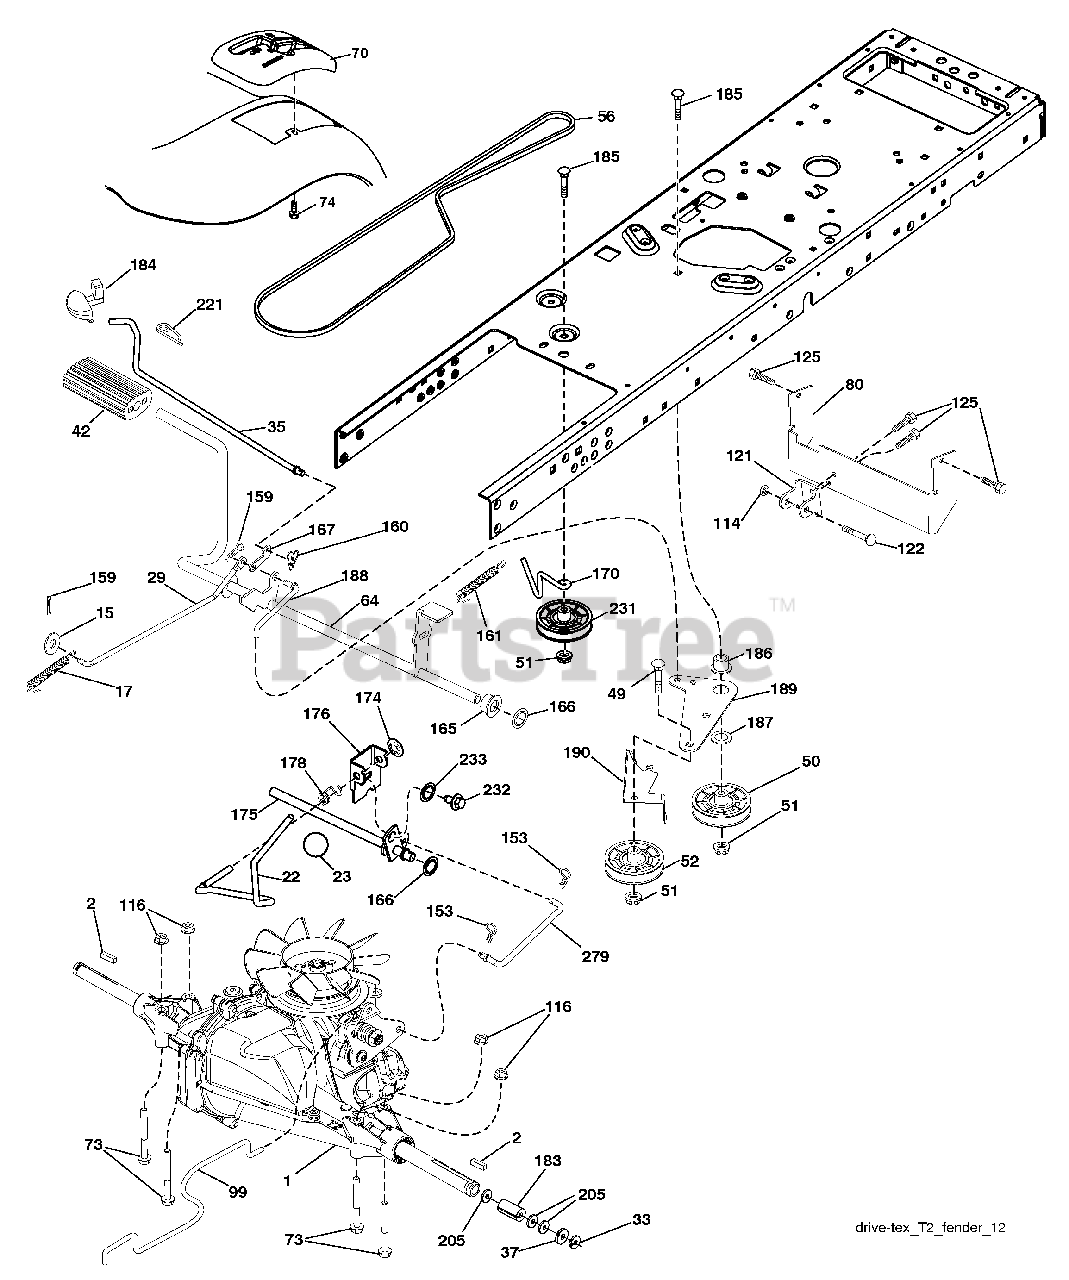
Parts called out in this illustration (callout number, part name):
1	Transaxle, Hydro Gear T2 AABC-1X1A-1GX1 (Internal Parts Not Available)
2	Key Square
15	Washer 13/32 x 13/16 x 16 Ga.
17	Spring, Brake
22	Rod Shift
23	Knob Deluxe
29	Rod, Brake
33	Ring E
35	Rod, Brake, Park
37	Washer 25/32 x 1-1/4 x 16 Ga.
42	Cover, Foot Pedal
49	Bolt
50	Pulley Idler Flat
51	Lock Nut 3/8-16
52	Idler V-Groove 910" Offset
56	V-Belt, Drive
64	Shaft Asm. Pedal Brake Control
70	Console
73	Bolt Hex 5/16-18 Gr. 5
74	Screw 1/4 x 1/2
80	Strap Torque
99	Rod Spring Bypass
114	Nut Lock 5/16-18 unc
116	Nut Lock Hex Flange 5/16-18
121	Bracket Strap Torque
122	Bolt 5/16-18 x 2.50
125	Screw 5/16-18 x 3/4
153	Retainer Spring 1"
159	Pin Cotter 1/8 x 3/4
160	Retainer Clip
161	Spring, Return, Clutch
162	Adapter Transaxle
165	Bushing
166	Nut Push .625
167	Latch Brake Parking
170	Keeper Belt Centerspan
174	Nut Push
175	Shaft Asm Shift
176	Arm Clevis Rod Shift
178	Spring Shift
183	Spacer Axle
184	Handle Parking Brake
185	Bolt
186	Spacer Retainer
187	Washer
188	Link Clutch Ground Drive
189	Bellcrank Ground Drive
190	Keeper Bellcrank Ground Drive
205	Washer 25/32 x 1-5/8 x 16 Ga.
221	Retainer Spring Clip Handle
231	Idler V-Groove 1.688" Offset
232	Bolt 7/16-14 x 1 Gr. 5
233	Washer Serrated
279	Link Shift
